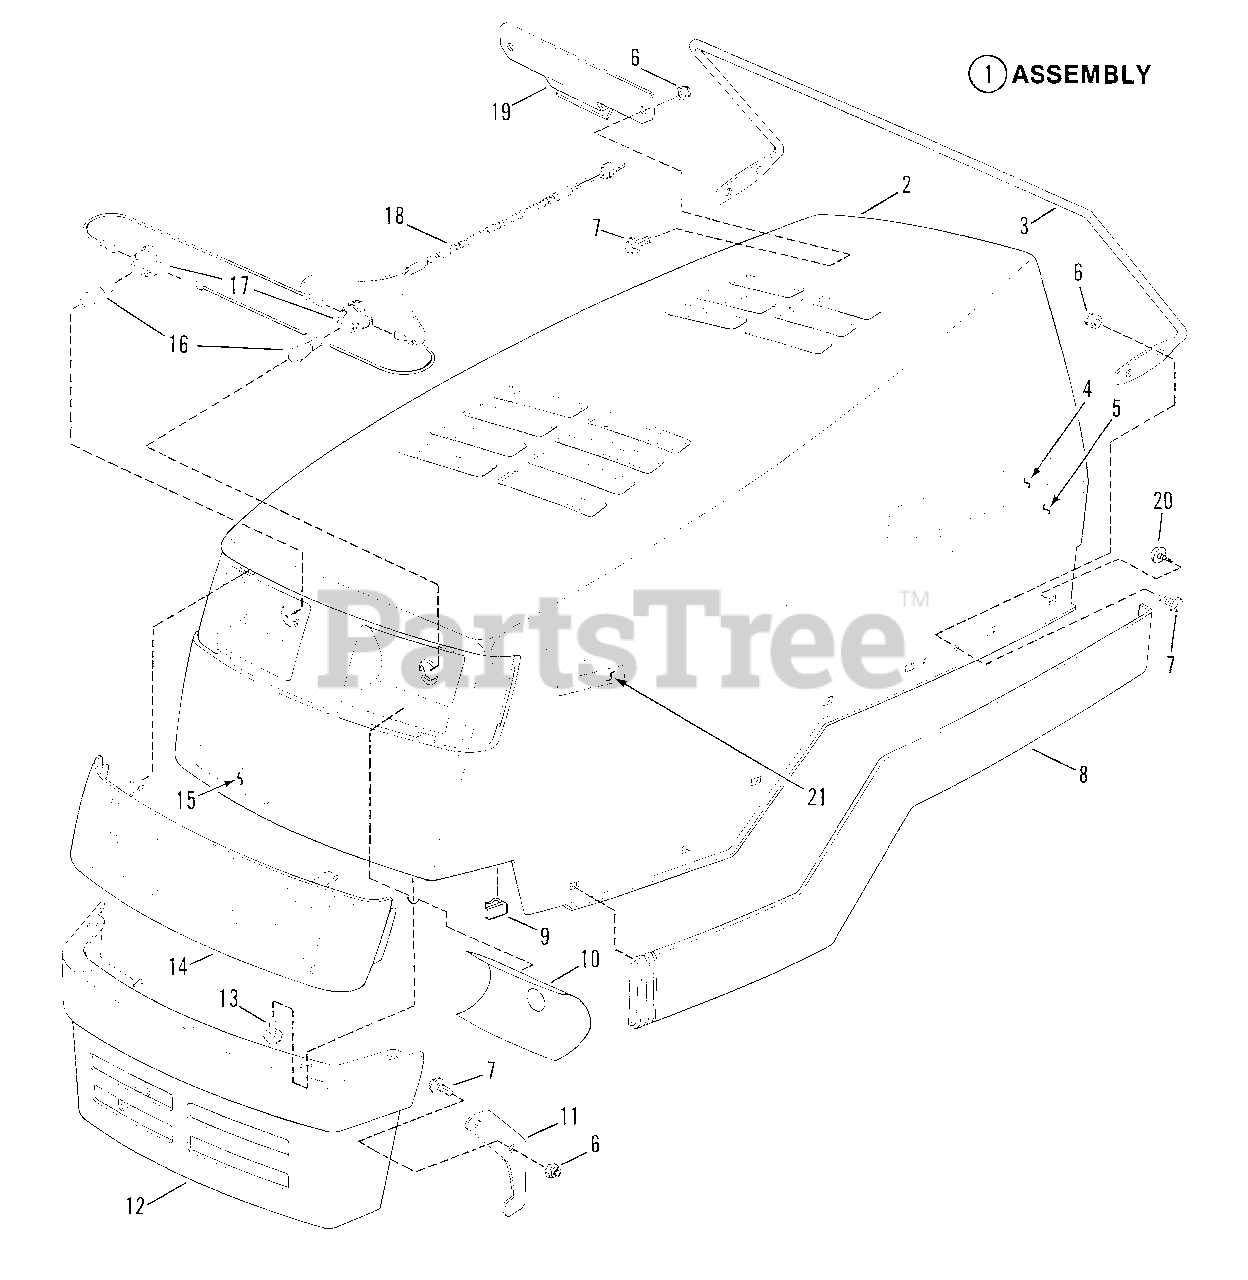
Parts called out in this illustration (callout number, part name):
1A	HOOD ASSEMBLY
1B	KIT, LTH Hood
3	ROD, Hood Latch
4	DECAL-SNAPPER, Molded Logo
5	DECAL, Stripe
6	LOCKNUT, 1/4-20 Hex
7	SCREW, 1/4-20 x 5/8" Torx, Truss Hd.
8	BUMPER
9	CLIP, Wiring Harness
10	DECAL, Reflect
11	BRACKET, Latch Hook
12	BUMPER, Front
13	SCREW, #12 x 1/2"
14	LENS
15	DECAL-SNAPPER, Molded Logo
16	BULB, Headlights
17	SOCKET, Headlight Bulb
18	HARNESS, Headlight Wiring
19	CLIP, Spring Latch
20	FASTENER
21	DECAL, Model, LT12D33
